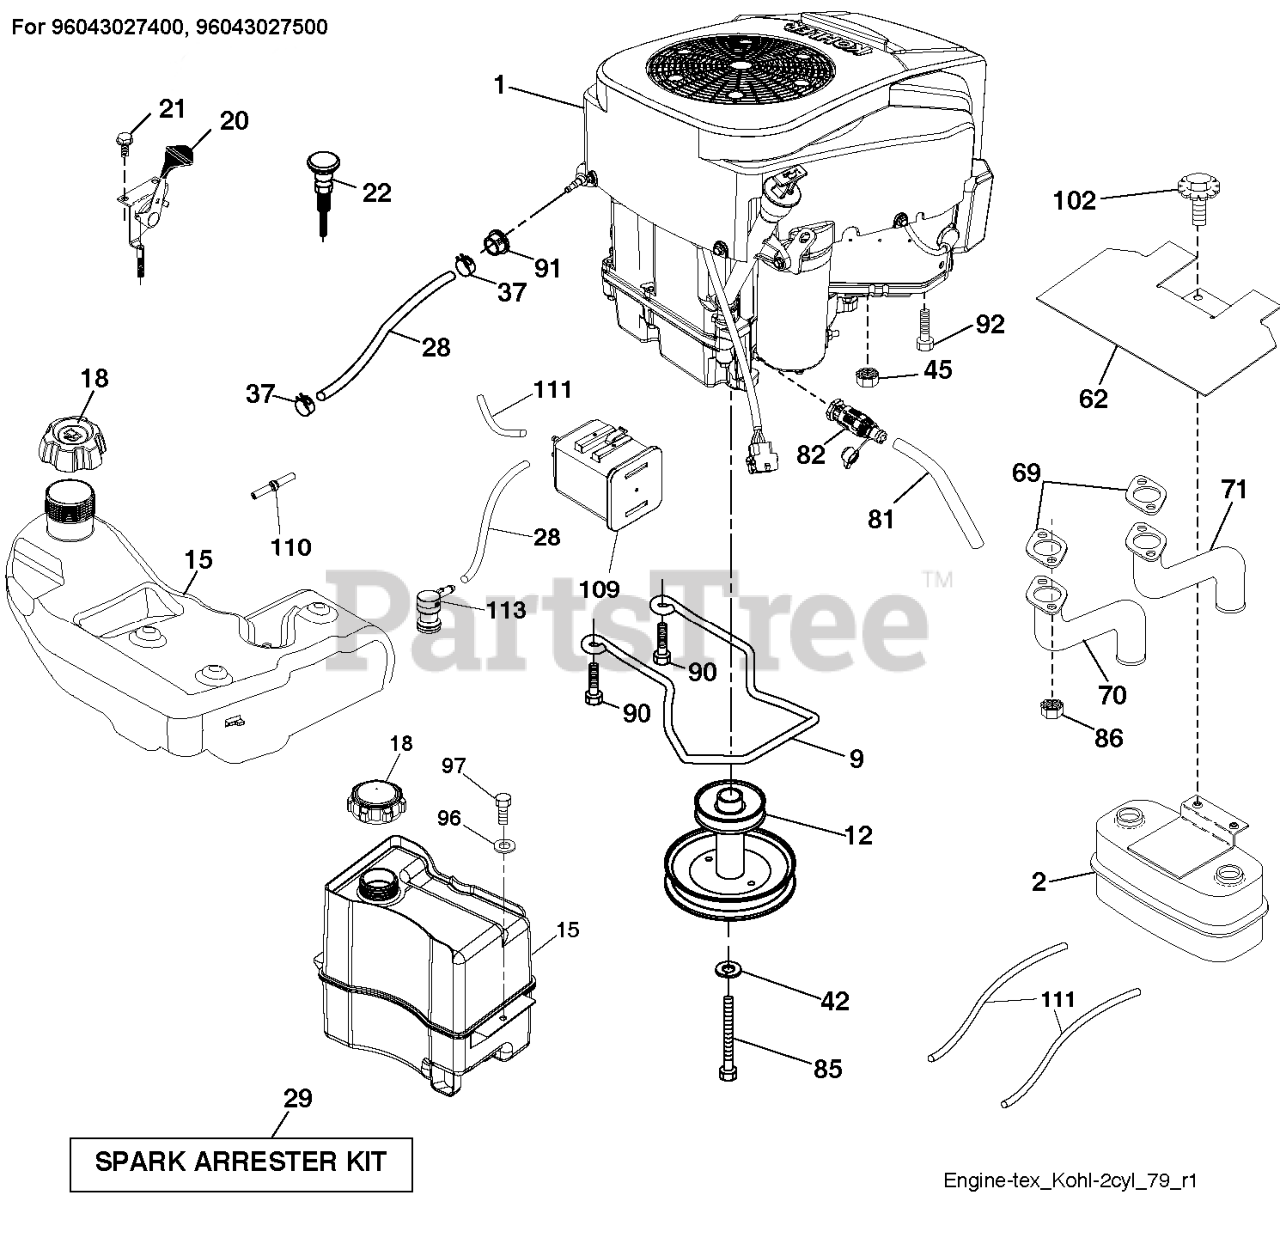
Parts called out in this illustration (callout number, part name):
2	MUFFLER.ASM.TWIN.MNTG.BRACKET
9	KEEPER.BELT.ENG.4.25"2.BLT.431
12	ENGINE.PULLEY
15	Tanks
15	FUEL TANK
18	CAP.2.25'.VENTED.TETHER .EPA
18	CAP ASSY FUEL 3" GRAY
18	FUEL CAP
20	CONTROL.THROTTLE.LH.COBRA.KNOB
21	SCREW.#10 X 0.750.BOS
22	CONTROL.CHOKE.ERGO.PUSH-IN.BLA
28	HOSE 1/4" LOW PERMEATION FUEL
29	KIT.SPARK ARRESTOR 794945 B&S
37	HOSE CLAMP
45	NUT
62	SHIELD.HEAT.MUFFLER
69	GASKET.EXHAUST.KOHL.CV18-CV26
70	PIPE.EXHAUST.LH.CV18/20
71	PIPE.EXHAUST.RH.CV18/20
81	TUBE, DRAIN OIL ASM.
82	VALUE.OIL.DRAIN
85	BOLT.HEX.7/16-20X4.GR5.1.5BLUE
86	SCREW.SOCKET HD.5/16-1
86	Screws
90	SCREW 3/8-16X1
91	BUSHING.1.375OD
92	SCREW 3/8-16X1
96	WASHER
97	SCREW HEXWSHR 1/4-20X3/4
102	SCREW
109	CANNISTER, CARBON
110	VALVE.ASM.ANTI-SLOSH
111	RP PURGE LINE
113	VALVE.SLANT.CARTRDG.90 DEG.TEX
